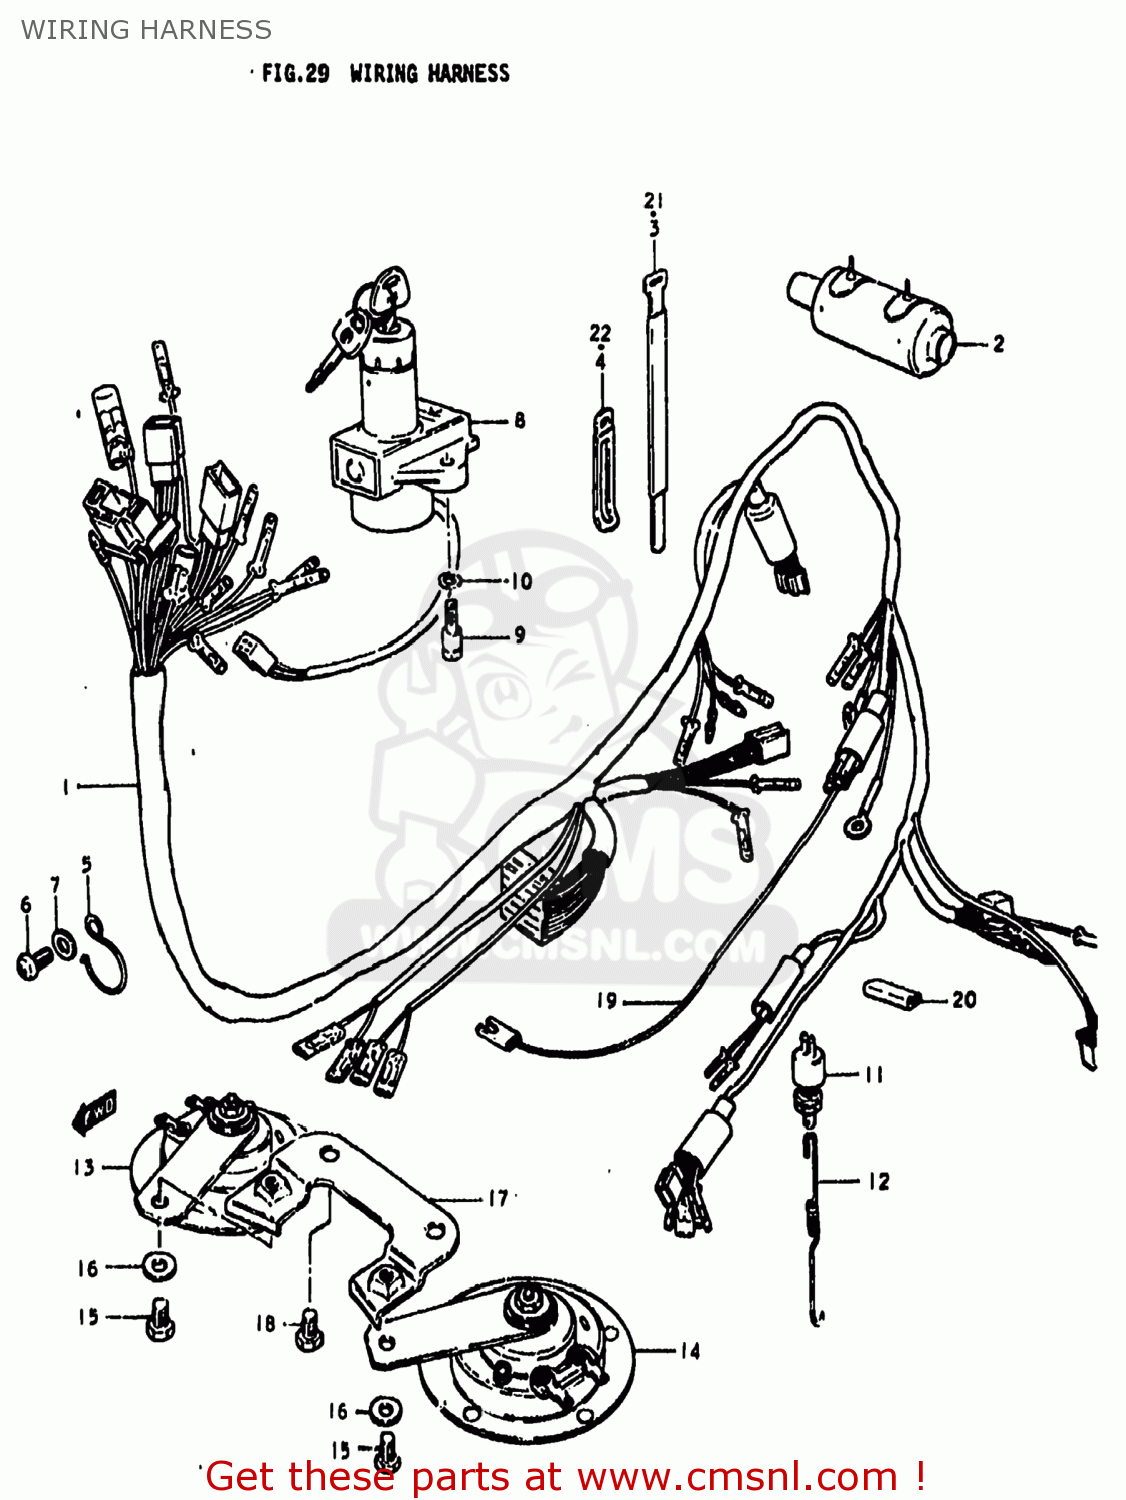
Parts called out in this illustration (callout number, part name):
1	HARNESS,WIRING
2	BOOT,WIRING HARNESS
3	CLAMP
4	CLAMP
5	GUIDE,WIRING HARNESS
6	SCREW 6X12
7	WASHER
8	LOCK ASSEMBLY,STEERING
9	BOLT
10	LOCK WASHER
11	SWITCH ASSY,BRAKE LAMP
12	SPRING
13	HORN ASSY
14	HORN ASSEMBLY,HIGH PITCH
15	BOLT
16	WASHER
17	BRACKET,HORN
18	BOLT 8X12
19	WIRE
20	PROTECTOR,WIRING HARNESS
21	CLAMP(L:120)
22	CLAMP
